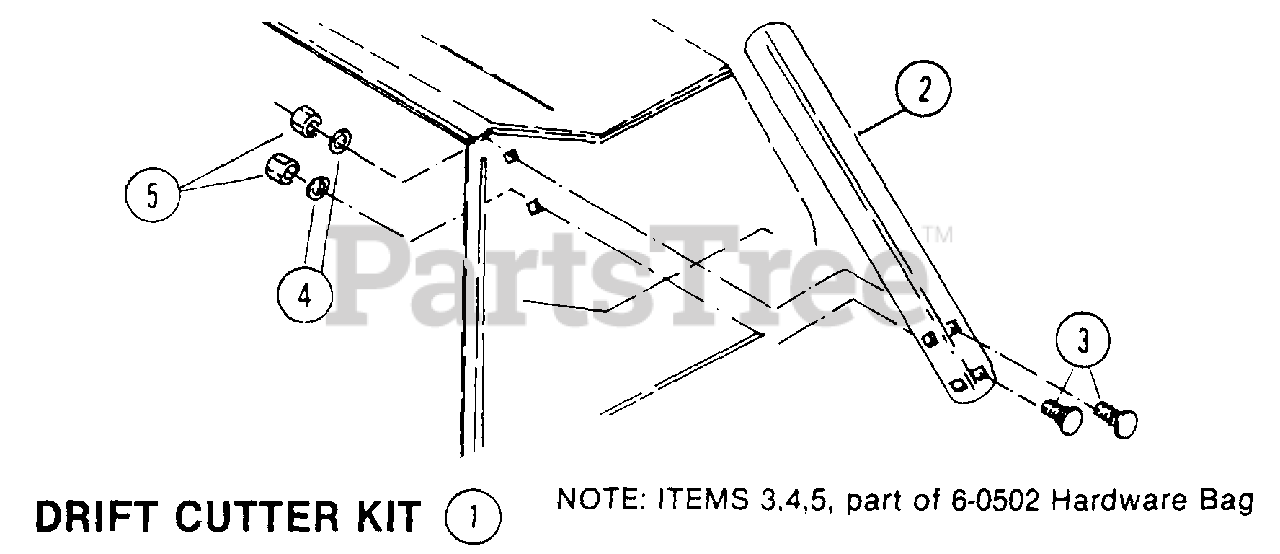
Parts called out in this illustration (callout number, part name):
1	KIT, Drift Cutter
2	CUTTER, DRIFT
3	BOLT, 5/16Cx3/4 Carriage
4	LOCKWASHER, 5/16 Split
5	NUT, 5/16 Hex
